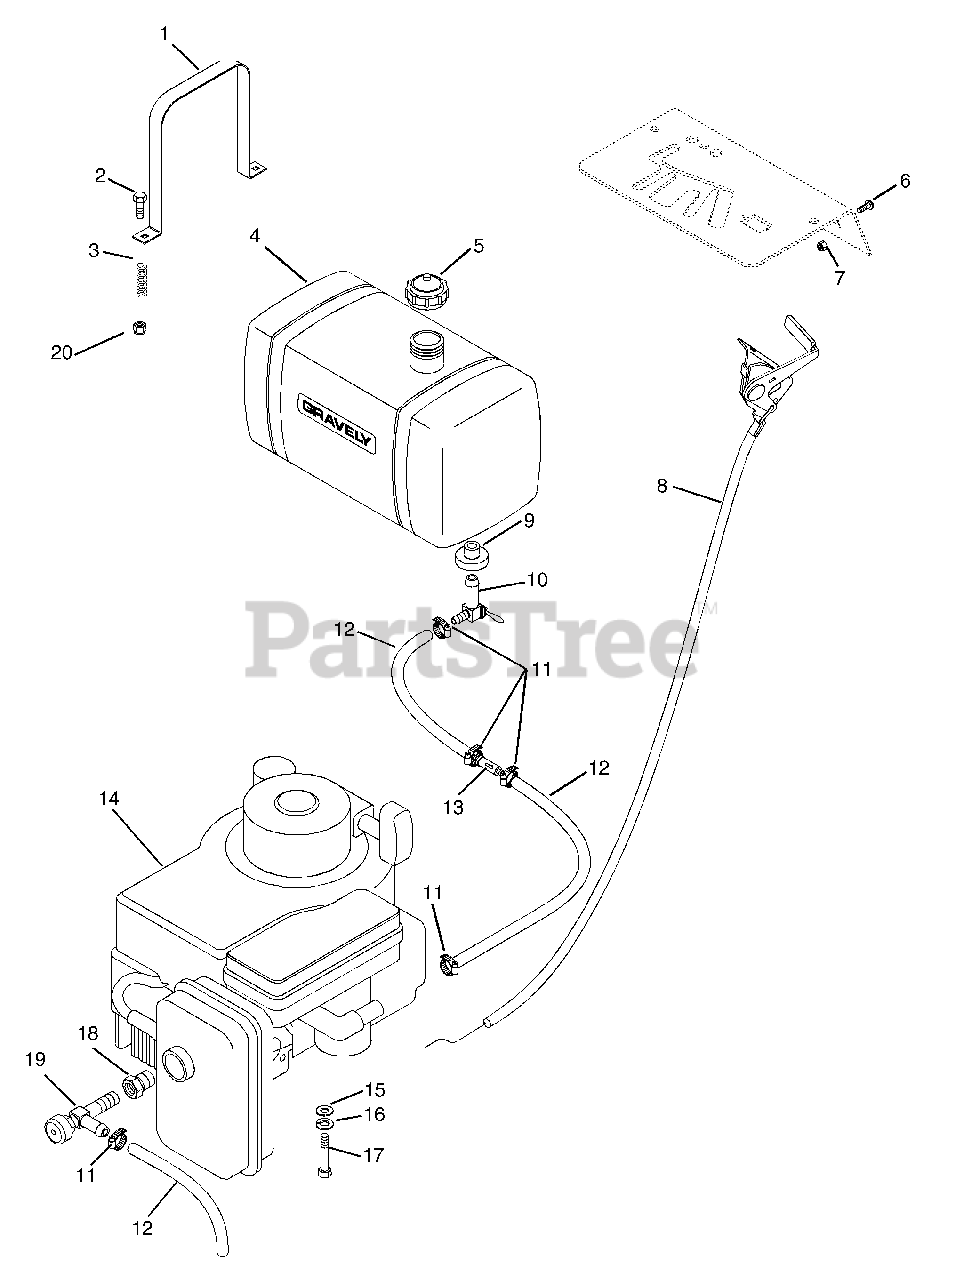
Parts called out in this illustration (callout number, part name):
1	Strap, Fuel Tank
2	Bolt-Hex .25-20 x .63
3	Nut-Locking-Nylon .250-20
4	Tank, Fuel Gravely Pro
5	Cap, Fuel Tank
6	Screw-Machine 10-24 x .50
7	Nut-Locking 10-24
8	Assembly Throttle Control/Cable
9	Bushing
10	Valve, Ball Shut-Off
11	Hose Clamp
12	Gas Line-Bulk
13	Filter, Fuel
14	Engine - 14 HP Kawasaki
15	Washer-Flat-Steel .344 x .688 x .065
16	Washer-Lock .313 x .078
17	Bolt-Hex M8 x 1.25 x 30mm
18	Adapter, Oil Drain
19	Cock, Oil Drain
20	Spring, Compression .125 x .78 x 1.00
